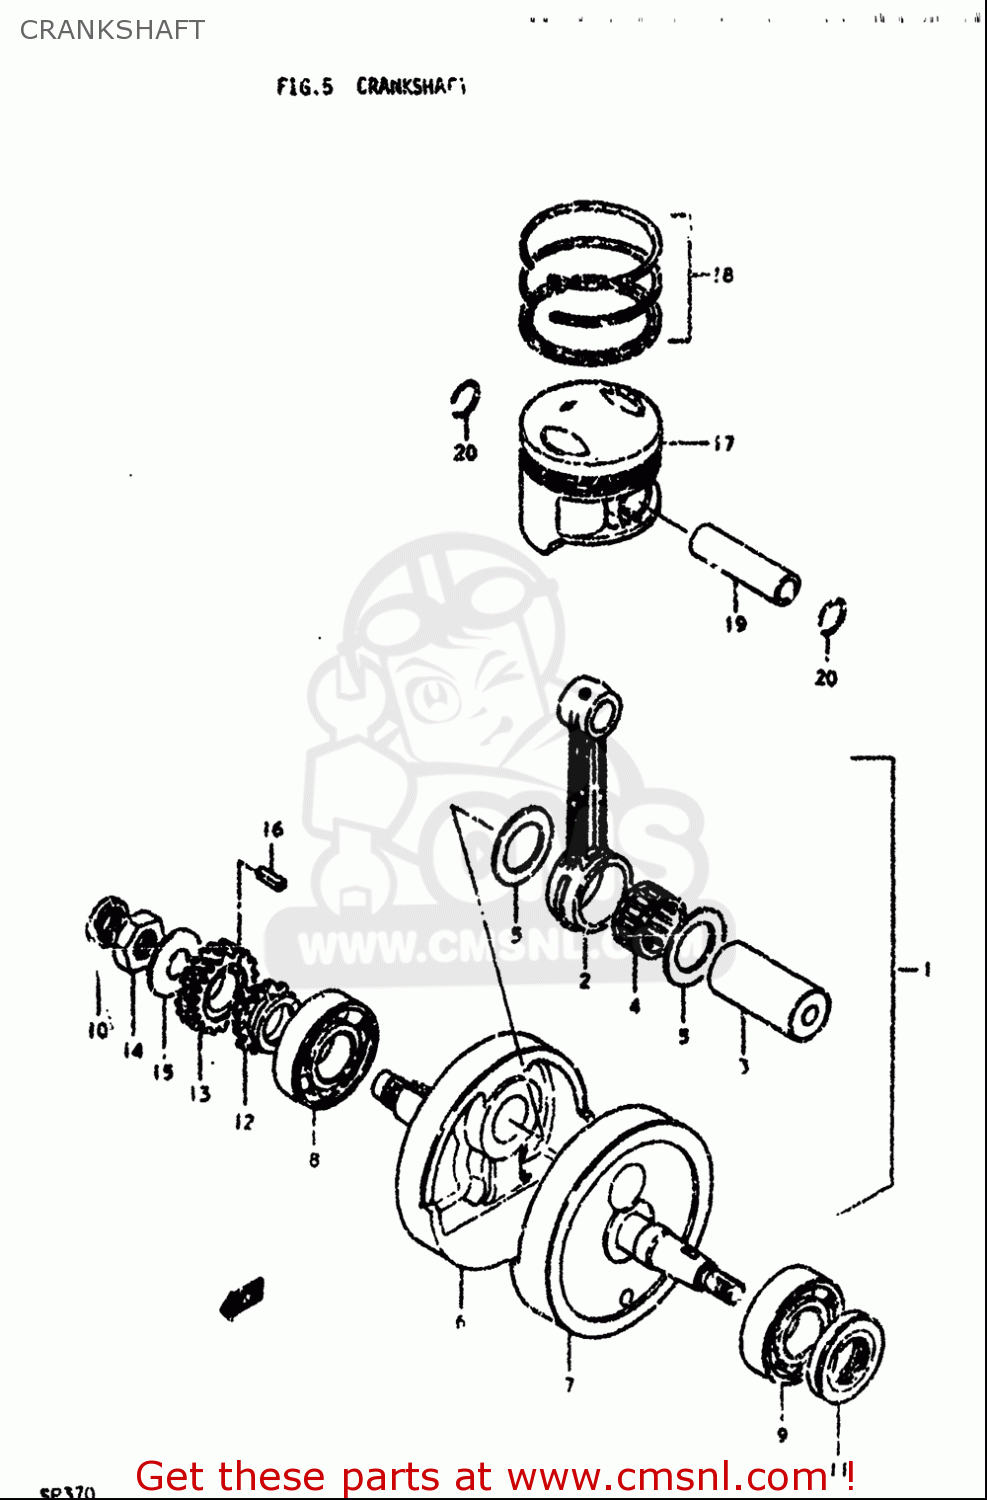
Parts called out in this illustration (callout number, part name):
5	WASHER (32X50X1)
8	BEARING(30X72X19)
9	BEARING(30X72X19)
10	SEAL,OIL(16X30X6)
11	SEAL,OIL(30X58X7)
14	NUT
15	WASHER
16	KEY
17	PISTON SET
18	RING SET,PISTON
19	PIN,PISTON
20	CIRCLIP,PISTON PIN
